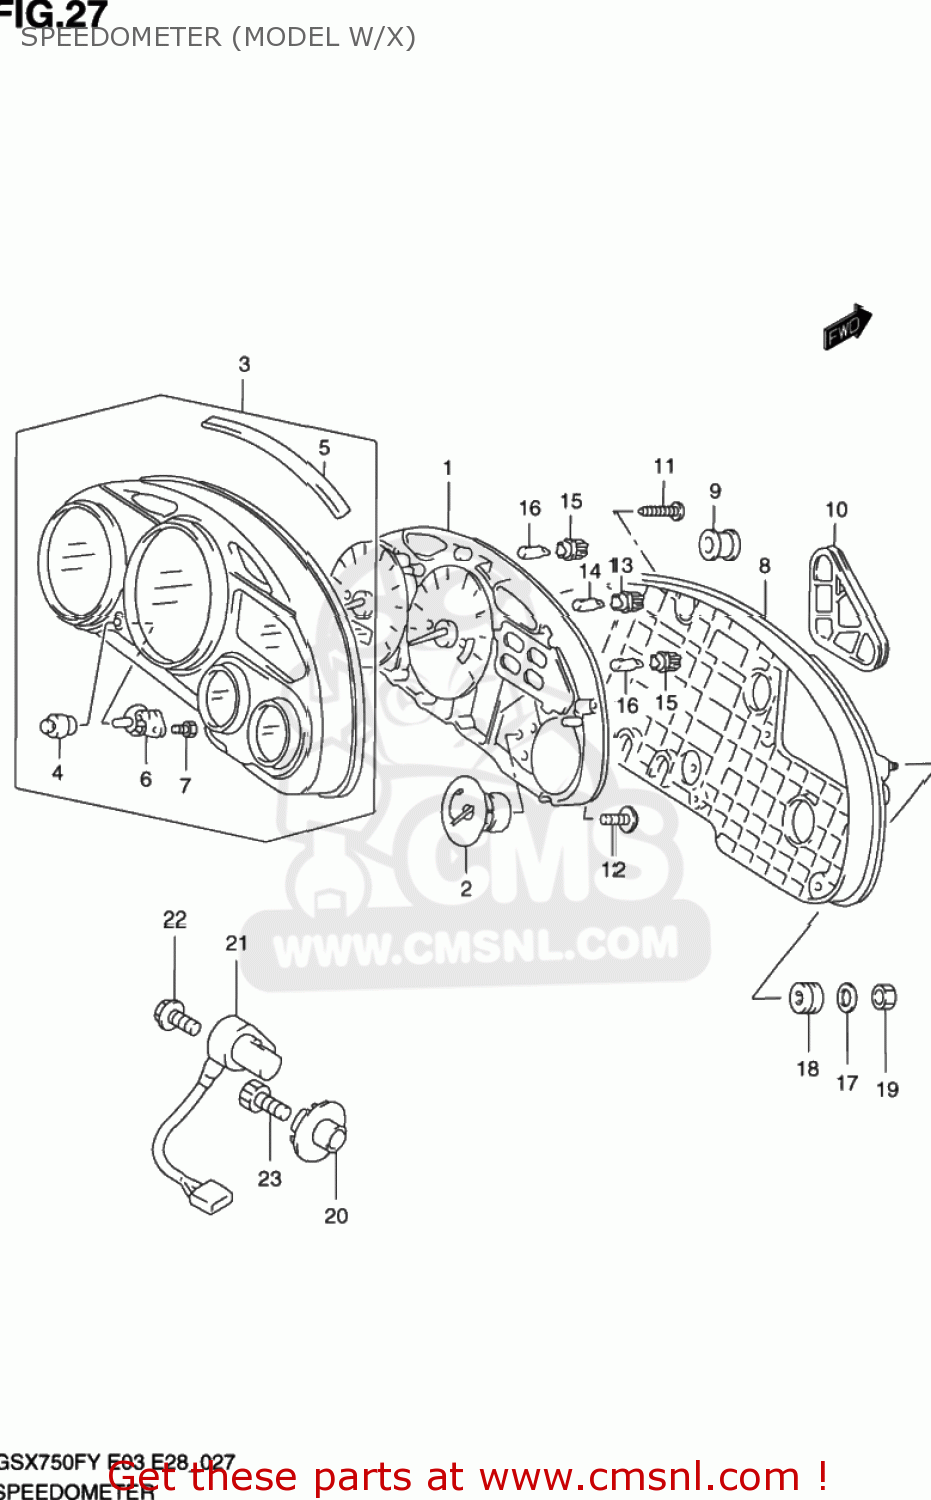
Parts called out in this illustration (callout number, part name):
1	SPEEDOMETER
2	FUEL METER ASSEMBLY
3	VISOR ASSY
4	SWITCH,GUM
5	PACKING (NAS)
6	ATTACHMENT,SWITCH
7	SCREW(3X10)
8	CASE ASSEMBLY
9	CAP,BLIND NO.1
10	CAP,BLIND
11	SCREW
12	SCREW
13	SOCKET(T:6.5)
14	BULB(12V1.7W,T6.5)
15	SOCKET
16	BULB(14V1.4W,T5)
17	WASHER(6.5X22X1.6)
18	CUSHION
19	NUT 6MM
20	ROTOR,SPEED
21	SENSOR,SPEED
22	BOLT
23	BOLT
